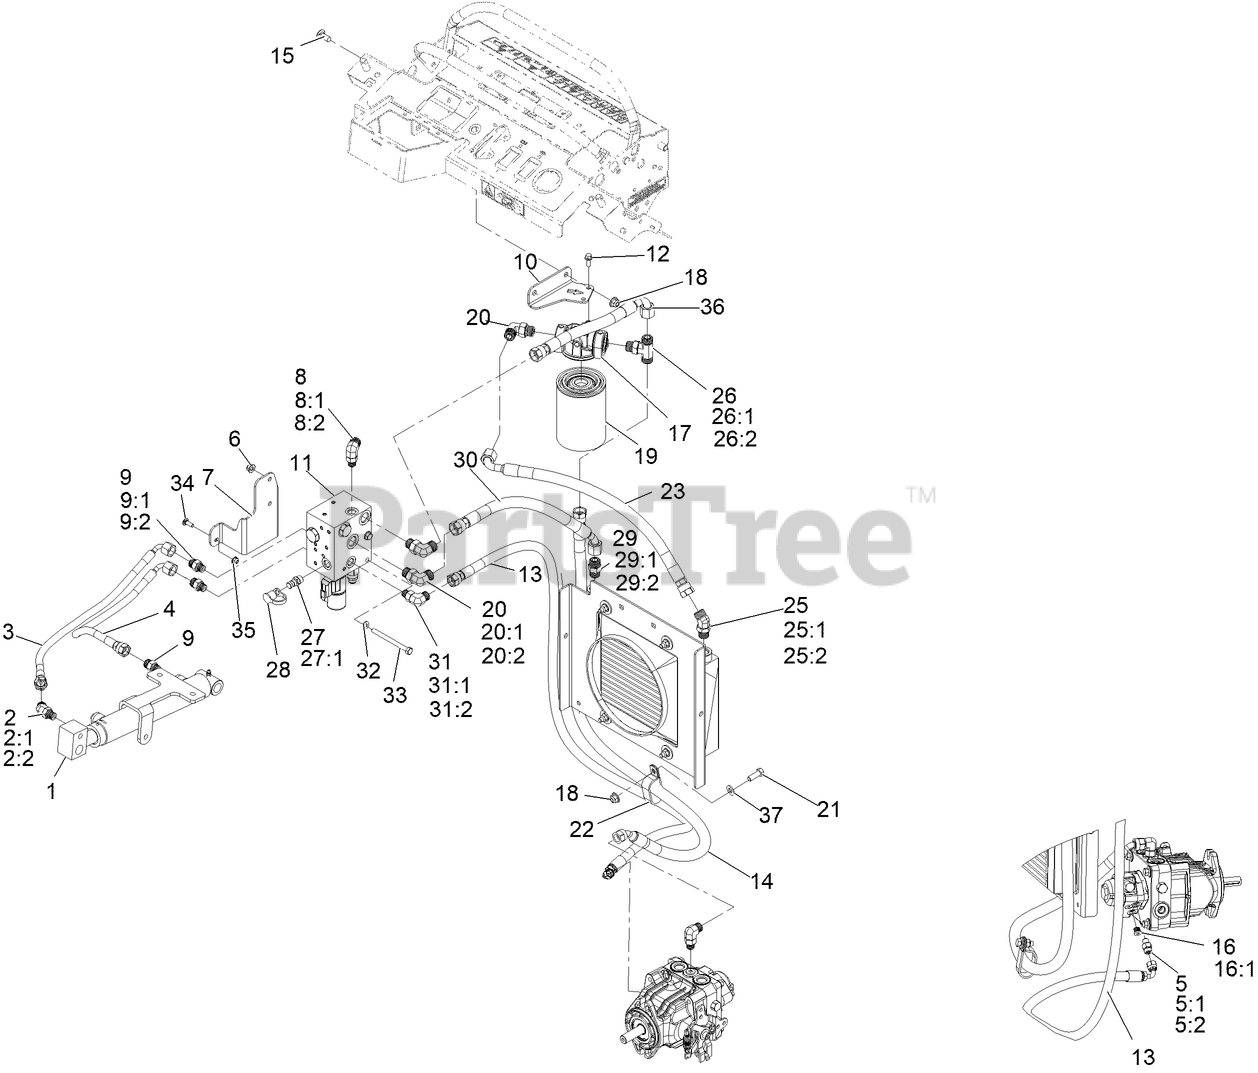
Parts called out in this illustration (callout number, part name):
1	CYLINDER-LIFT
2	FITTING-ELBOW, 45 DEG
2:1	O-RING
2:2	O-RING
3	HYDRAULIC HOSE ASM
4	HYDRAULIC HOSE ASM
5	FITTING-STRAIGHT
5:1	O-RING
5:2	O-RING
6	NUT-HF, NI
7	BRACKET-VALVE, CONTROL
8	Fitting-HYD, 90 DEG
8:1	O-RING
8:2	O-RING
9	FITTING-STRAIGHT
9:1	O-RING
9:2	O-RING
10	BRACKET-FILTER
11	MANIFOLD-VALVE, CONTROL
12	SCREW-HHF
13	HYDRAULIC HOSE ASM
14	HYDRAULIC HOSE ASM
15	SCREW-CARR
16	PLUG ASM
16:1	O-RING
17	HEAD-FILTER
18	NUT-HF, NI
19	HYDRAULIC OIL FILTER ASM W/DECAL
20	FITTING-ELBOW, 90 DEG
20:1	O-RING
20:2	O-RING
21	SCREW-HH
22	Clamp-R, Double
23	HYDRAULIC HOSE ASM
25	FITTING-HYD, 45 DEG
25:1	O-RING
25:2	O-RING
26	FITTING-HYD, TEE
26:1	O-RING
26:2	O-RING
27	FITTING-DIAGNOSTIC
27:1	O-RING
28	CAP-DUST
29	FITTING-STRAIGHT
29:1	O-RING
29:2	O-RING
30	HYDRAULIC HOSE ASM
31	FITTING-ELBOW, 90 DEG
31:1	O-RING
31:2	O-RING
32	WASHER-PLAIN
33	SCREW-HH
34	BOLT-CARR
36	HYDRAULIC HOSE ASM
37	WASHER-FLAT
